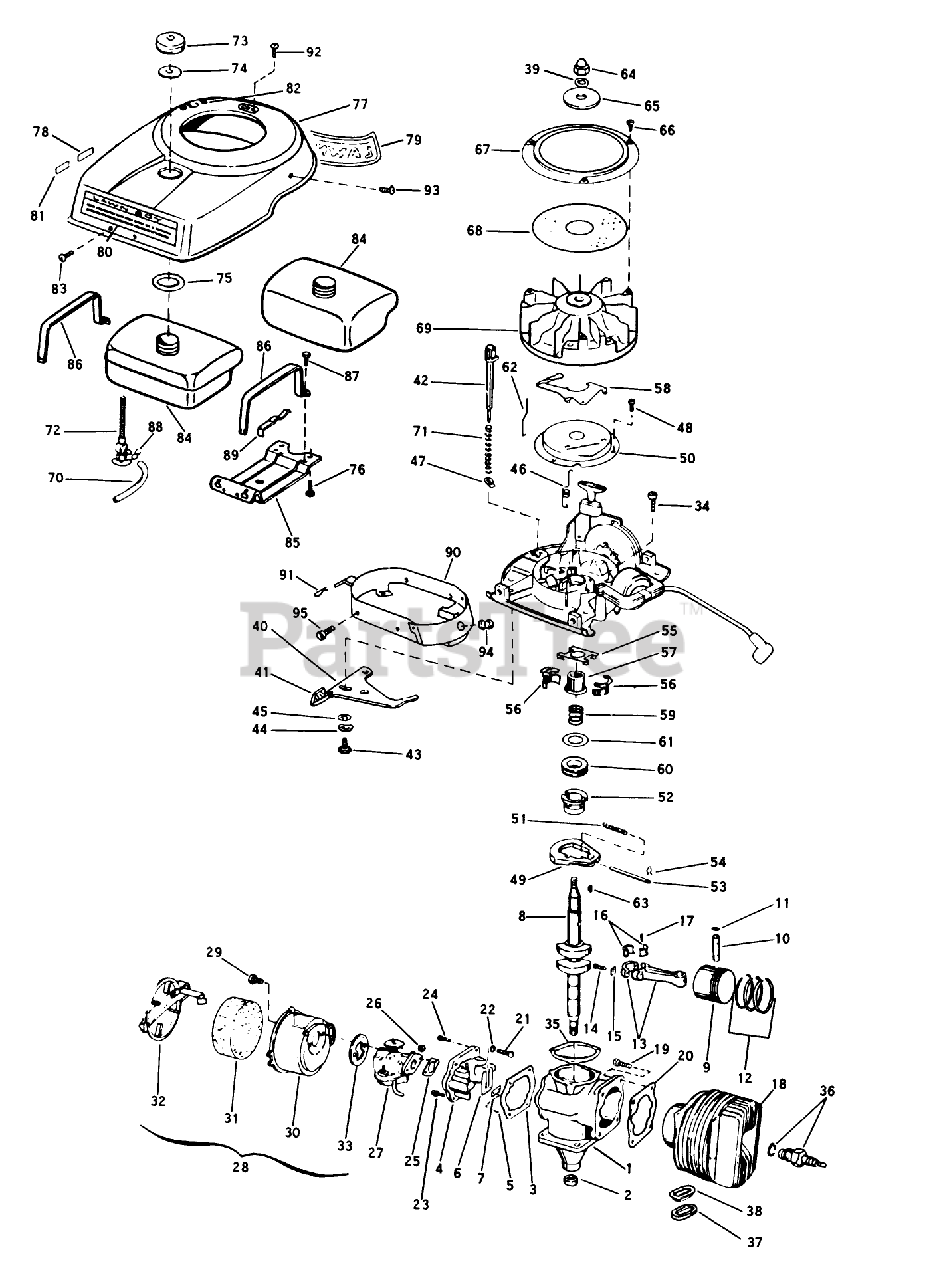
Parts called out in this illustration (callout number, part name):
7	PLATE-BACKUP, REED
11	RING-RETAINING
16	LINER ASM
20	GASKET S
23	SCREW S
24	SCREW S
25	GASKET S
26	STOP NUT
29	SCREW S
31	AIR FIL.ELEM S
35	GASKET S
36	Spark Plug
37	GASKET S
48	SCREW S
49	FLYWEIGHT S
50	DUST COVER S
51	SPARK ADV. SPRING S
52	SPARK ADV. S
53	PIN,SPARK ADV. S
54	SPARK ADJ. SPRING
57	COLLAR S
58	LEVER-GOVERNOR S
59	SPRING S
60	THRUST COLLAR S
67	Ring-Flywhl. Scrn.
70	GAS LINE
71	SPRING S
72	VALVE&SCREEN SM
76	SCREW S
84	Gas Tank
88	CLAMP - HOSE S
89	SPRING
93	SCREW S
94	NUT-CLIP
95	SCREW S
